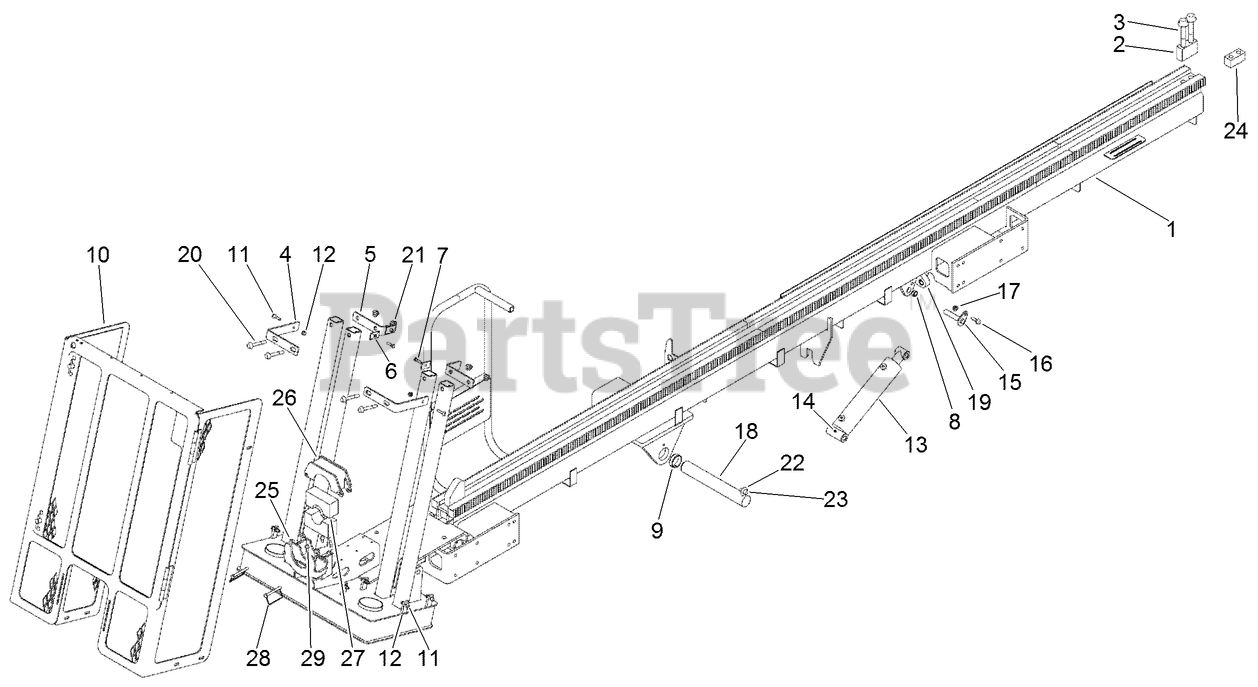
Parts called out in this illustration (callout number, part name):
1	WELDMENT - Thrust Frame
2	STOP BLOCK - Rear
3	SCREW-HHF
4	POST - Tie, Stakedown
5	HOLDER - Hose
6	PLATE-COVER, TWIN
7	BOLT-Hex, 5/16 NC x 1-1/4 inch
8	BUSHING-SPRG.75"IDX1.00"X .5"L
9	SPRING BUSHING - 2 ID x 2.25 OD x .75 Long
10	COVER - Stakedown
11	SCREW, METRIC FLANGE w/BODY - M8 x 35
12	NUT-TORQUE, PREVAILING
13	CYLINDER-HYDRAULIC
14	FITTING-Lube 1/4-28 Tpr SAE-LT .54 Long
15	PIN-FLAG
16	SCREW-HHF
17	NUT-FLANGE, NYLOCK
18	PIN ASSEMBLY - Boom
19	BUSHING-SPRING
20	SCREW, METRIC FLANGE w/BODY-M12 x 90
21	NUT-HHF, LOCK
22	PIN-RETAINER
23	SCREW-FLANGE
24	BLOCK - Tapped
25	WELDMENT - Rod Guide Bushing Bottom
26	WELDMENT - Rod Bushing Top
27	GUIDE-ROD, BUSHING
28	PIN-SELF LOCKING
29	SCREW, METRIC FLANGE w/BODY - M8 x 20
